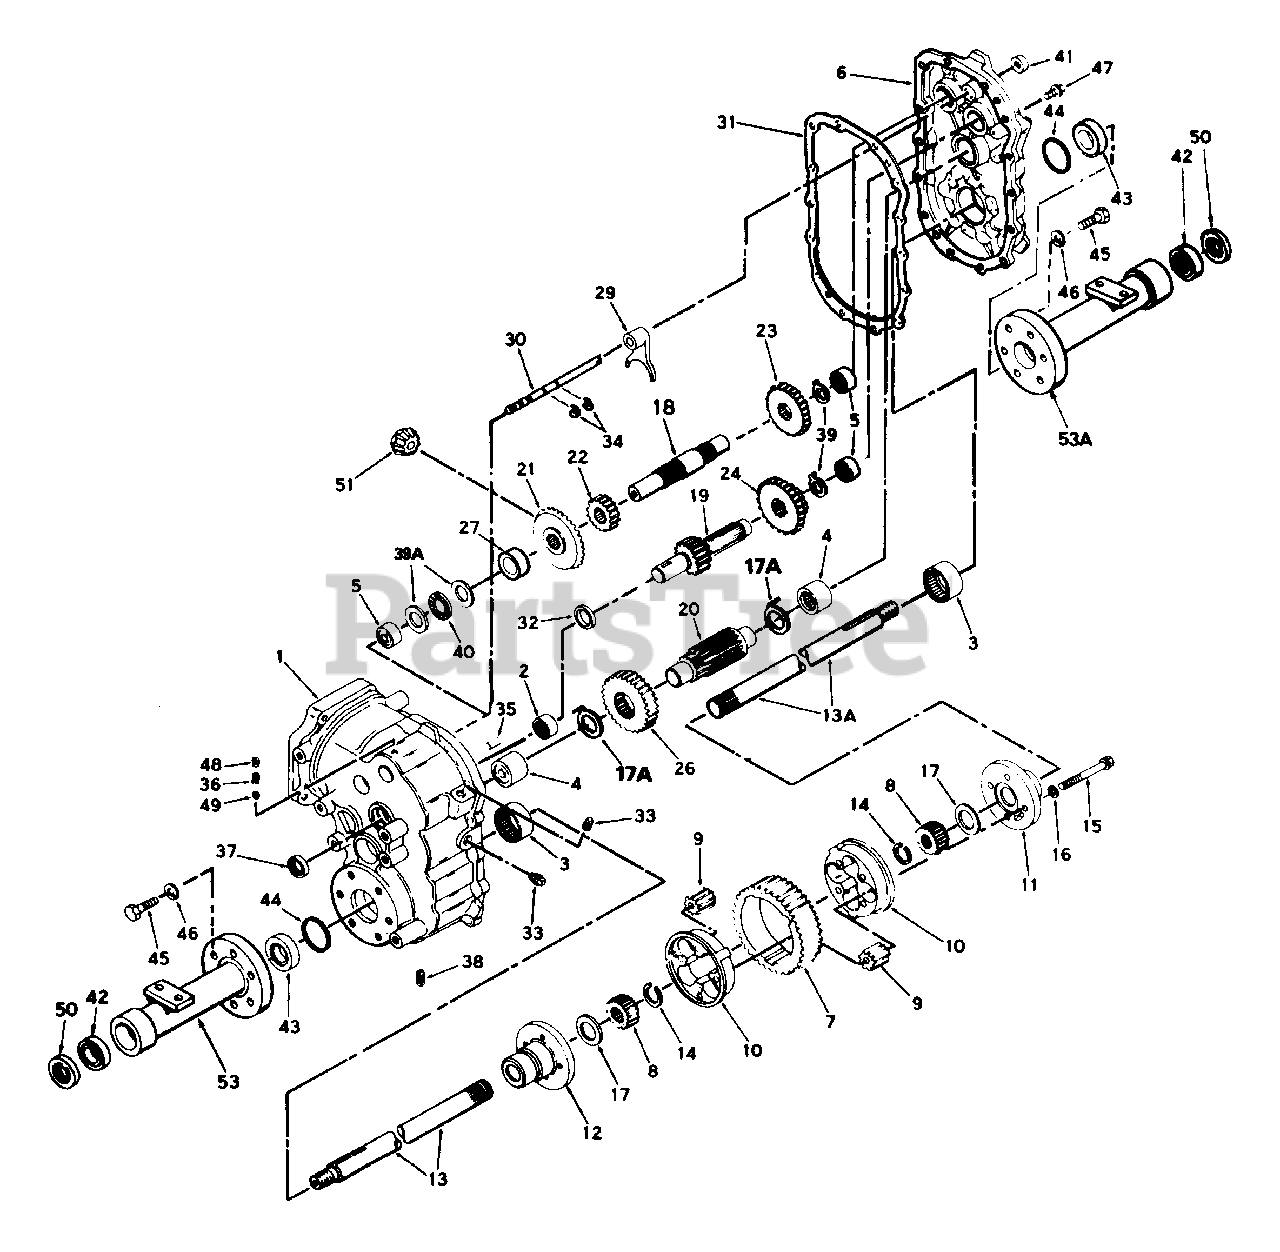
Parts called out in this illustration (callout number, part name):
1	Case Ass'y., Transaxle
2	Bearing, Needle
3	Bearing, Needle
4	Bearing, Needle
5	Bearing, Needle
6	Cover Ass'y., Transaxle
7	Gear, Ring
8	Gear, Side
9	Gear, Pinion
10	Core, Body
11	Carrier, Differential
12	Carrier, Differential
13	Axle, (18-17/64" Long)
13A	Axle, (15-29/64" Long)
14	Ring, Snap
15	Screw, Hex Hd. Mach., 3/8-16 x 3-3/8
16	Lock Washer, 3/8"
17	Washer, Thrust
17A	Washer, Thrust
18	Shaft, Counter
19	Shaft, Brake
20	Pinion, Output
21	Gear, Bevel (30 Teeth)
22	Gear, Spur (16 Teeth)
23	Gear, Spur (23 Teeth)
24	Gear, Cluster (20 and 27 Teeth)
26	Gear, Output (37 Teeth)
27	Spacer (55/64" Long)
29	Fork, Shift
30	Rod, Shift
31	Gasket, Case and Cover
32	Spacer
33	Plug, Pipe
34	Ring, Snap
35	Pin, Dowel
36	Spring
37	Seal, Oil
38	Plug, Magnetic Drain
39	Washer, Thrust
40	Bearing, Thrust
41	Seal, Oil
42	Bearing, Ball
43	Bearing, Thrust
44	Seal, Square Cut
45	Screw, Hex Hd. Mach., 1/2-13 x 1 1/2
46	Lock Washer, 1/2"
47	Screw, Hex Hd. Thd. Forming, 5/16-18 x 1
48	Screw, Set 1/4-20 x 1/2
49	Ball, Steel
50	Seal, Oil
51	Pinion, Bevel
53	Housing, Axle (9-1/4" Long)
53A	Housing, Axle (7-5/16" Long)
